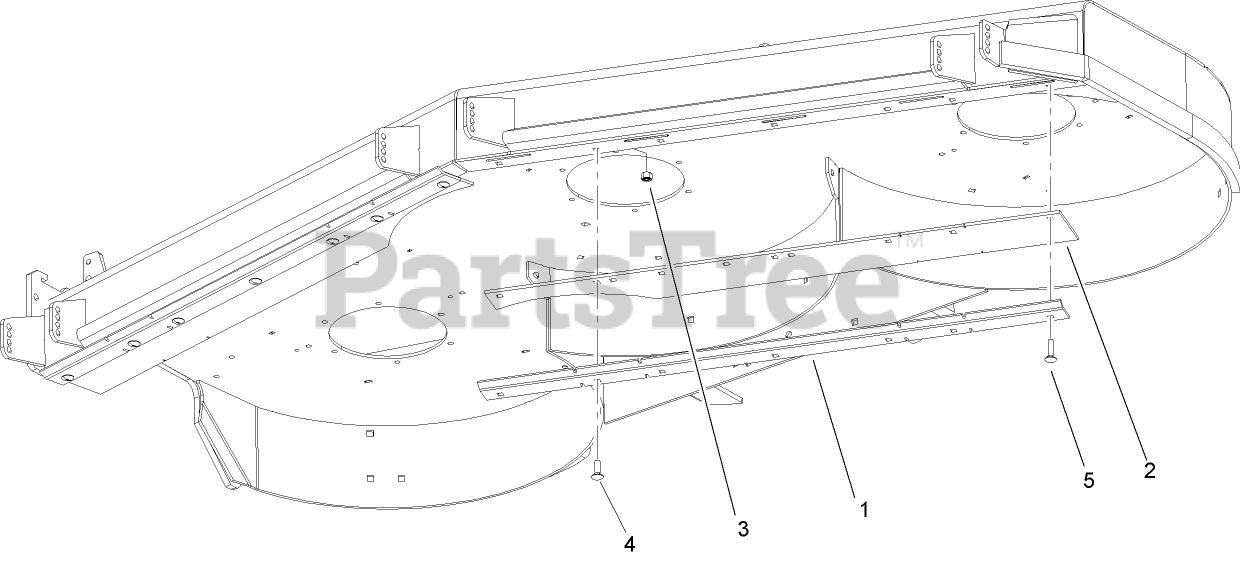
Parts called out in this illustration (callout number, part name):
1	SKID-SKIRT
2	SKIRT-RUBBER, FRONT
3	NUT-LOCK, NI
4	BOLT-CARR
5	SCREW-CARR
